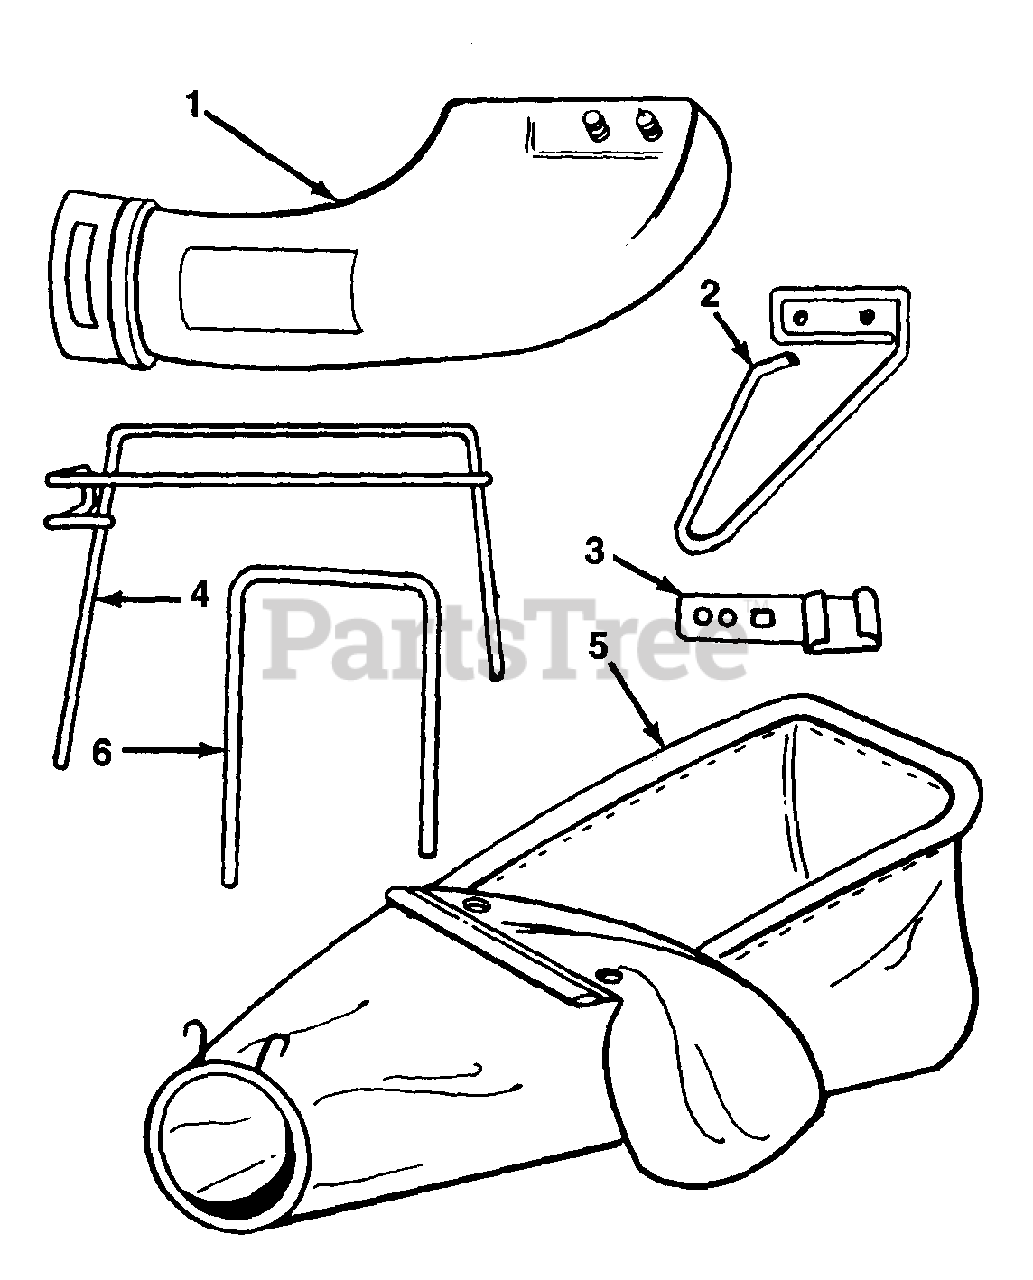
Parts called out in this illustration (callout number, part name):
1	Plastic Chute
2	Chute Mounting Bracket w/Wire
3	Handle Bracket
5	Bag w/Clamp Ring
6	Upper Support Tube
